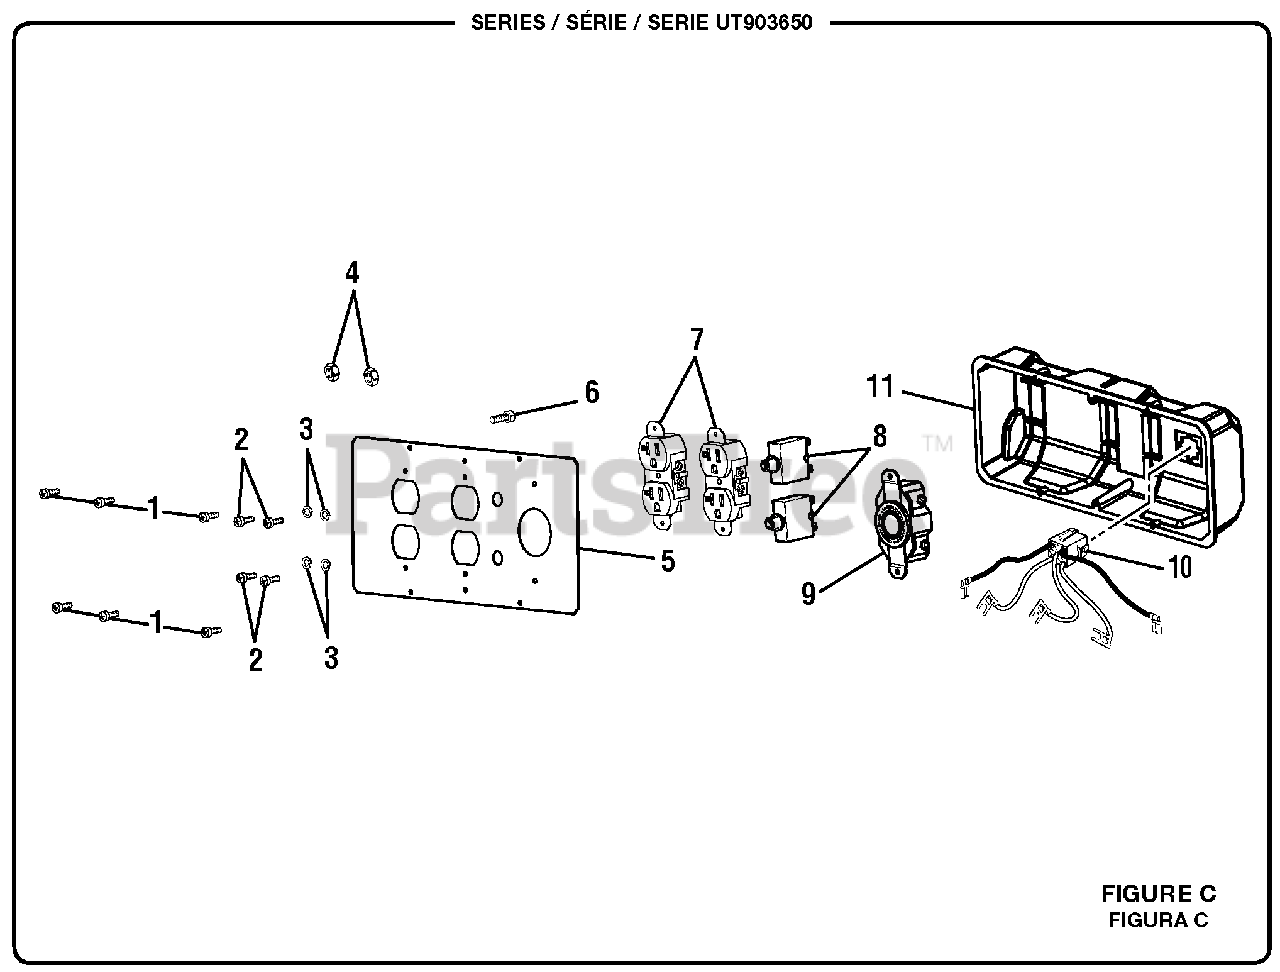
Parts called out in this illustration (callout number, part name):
1	Screw (6-20 x 3/8 in)
2	Screw (M3 x 6 mm)
3	Lock Washer
4	Hex Nut (1/4-20)
5	Cover Plate
6	Screw (1/4-20 x 5/8 in, Hex Hd)
7	Duplex Receptacle (120 Volt)
8	Circuit Breaker (15 Amp, 125 Volt)
9	Twist Lock Receptacle (120/240 Volt, 20 Amp)
10	Connector w/Leads
11	Rear Control Panel
